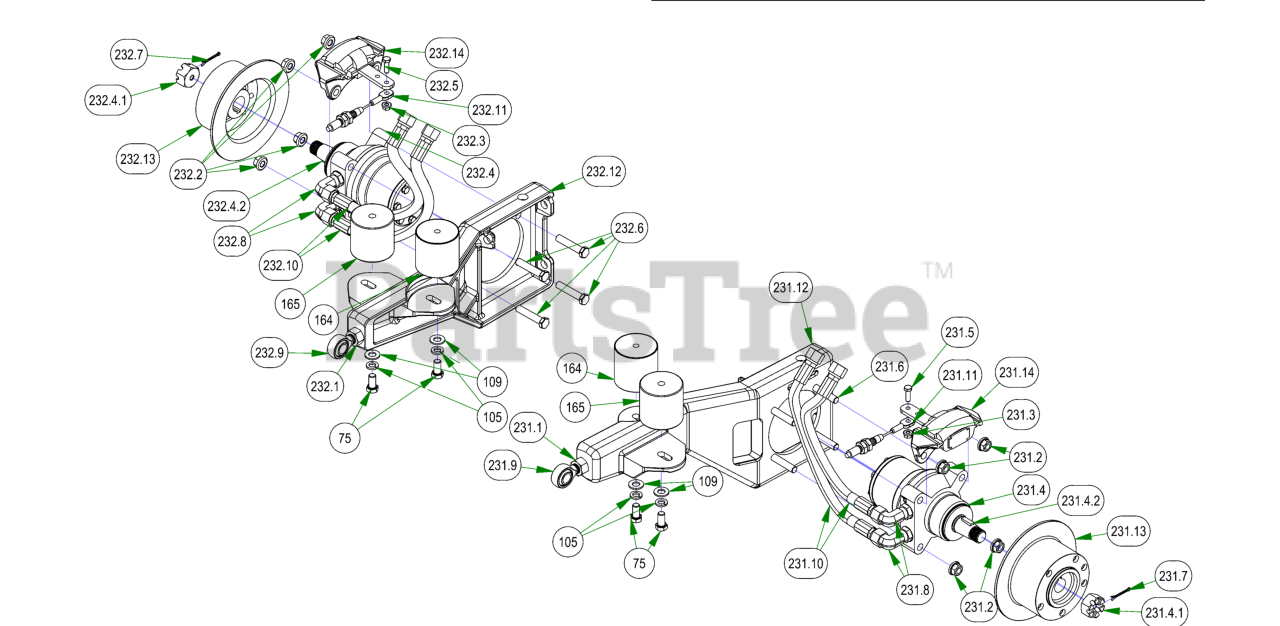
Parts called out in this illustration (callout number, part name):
4	3/4-10 NYLON INSERT LOCKNUT ZINC
13	1/2-13 HEX NUT ZINC
14	5/8-11 NYLON INSERT LOCKNUT ZINC
52	M6-1.0 X 16MM DIN 933 HEX TAP BOLT (CL 8.8) ZINC
57	3/4-10 X 2-1/2 HEX CAP SCREW (GR.5) ZINC
59	5/8-11 X 2-3/4 HEX CAP SCREW (GR.5) ZINC
67	All Thread
75	1/2-13 X 1 HEX CAP SCREW (GR.5) ZINC
79	1/2-13 NYLON INSERT JAM LOCKNUT ZINC
94	5/8-11 X 2-1/2 HEX CAP SCREW (GR.5) ZINC
96	1/2-20 x 60° Lug Bolts Zinc Grade 8
103	5/8" Flat Washer SAE Spec Grade 8
104	1/4SPLIT LOCKWASHER ZINC
105	1/2 SPLIT LOCKWASHER (GR.8) ZINC/YELLOW
109	1/2 SAE FLAT WASHER (1-1/16" OD) GR.8 ZINC YELLOW
115	1/4 USS FLAT WASHER (3/4 OD) ZINC
122	2019 Assy-26x12-12 Reaper Turf -10.5" Rim
123	2019 Assy-26x12-12 Reaper Turf-8.5" Rim
129	Spacer 1.125OD x .625 ID x .250 Length
133	5/8 SOLID SHAFT COLLAR (W/1 SET SCREW) ZINC
164	Vibration Mount-Blue Dot
165	Vibration Mount-Green Dot
166	5" PUMP PULLEY W/ SET SCREW
166.2	5/16-24 X 1/2 SOCKET SET SCREW KNURLED CUP POINT
173	Deck Idler Spring
180	2019 Rogue Pump Idler Assy
183	2019 Suspension Gusset Outlaw
190	2019 Rogue Pump Belt 68"
191	5MM X 36MM SQ MACHINERY KEY C1018 ROUNDED ENDS
200	2019 Suspension Radius Rod Assembly
201	2019 Suspension Radius Rod Assembly
224	2021 LH ROGUE HYDRO TANK LINE ASSY
225	2021 RH ROGUE HYDRO TANK LINE ASSY
231	2019 Rouge Trailing Arm LH Assy
231.1	3/4"-16 Fine Full Nut
231.2	1/2-13 Gr 8 Centerlock Flange Nut
231.3	5/16-18 NYLON INSERT FLANGE LOCKNUT ZINC
231.4	18cc Parker Wheel Motor- Left
231.4.1	1" Castle Nut for HydroGear Wheel Motor
231.4.2	Woodruff Key
231.5	5/16-18 X 1 HEX CAP SCREW (GR.5) ZINC
231.6	1/2-13 x 2.75 Gr. 8 Hex Head Bolt
231.7	1/8 X 1-1/2 COTTER PIN ZINC
231.8	2019 Rouge/Renegade Wheel Motor 90* Fitting #6801-10L
231.9	3/4-16 RH Male Rod End
231.10	20" Hydraulic Hose
231.11	2019 Short Brake Cable-Suspension Models
231.12	2019 Left Trailing Arm
231.13	Brake Disk
231.14	XP/AOS Left Brake Caliper
232	2019 Rogue Trailing Arm RH Assy
232.1	3/4"-16 Fine Full Nut
232.2	1/2-13 Gr 8 Centerlock Flange Nut
232.3	5/16-18 NYLON INSERT FLANGE LOCKNUT ZINC
232.4	18cc Parker Wheel Motor- Right
232.4.1	1" Castle Nut for HydroGear Wheel Motor
232.4.2	Woodruff Key
232.5	5/16-18 X 1 HEX CAP SCREW (GR.5) ZINC
232.6	1/2-13 x 2.75 Gr. 8 Hex Head Bolt
232.7	1/8 X 1-1/2 COTTER PIN ZINC
232.8	2019 Rouge/Renegade Wheel Motor 90* Fitting #6801-10L
232.9	3/4-16 RH Male Rod End
232.10	20" Hydraulic Hose
232.11	2019 Long Brake Cable-Renegade, Rogue
232.12	2019 Right Trailing Arm
232.13	Brake Disk
232.14	XP/AOS Right Brake Caliper
235	2023 Rogue Frame - Painted
